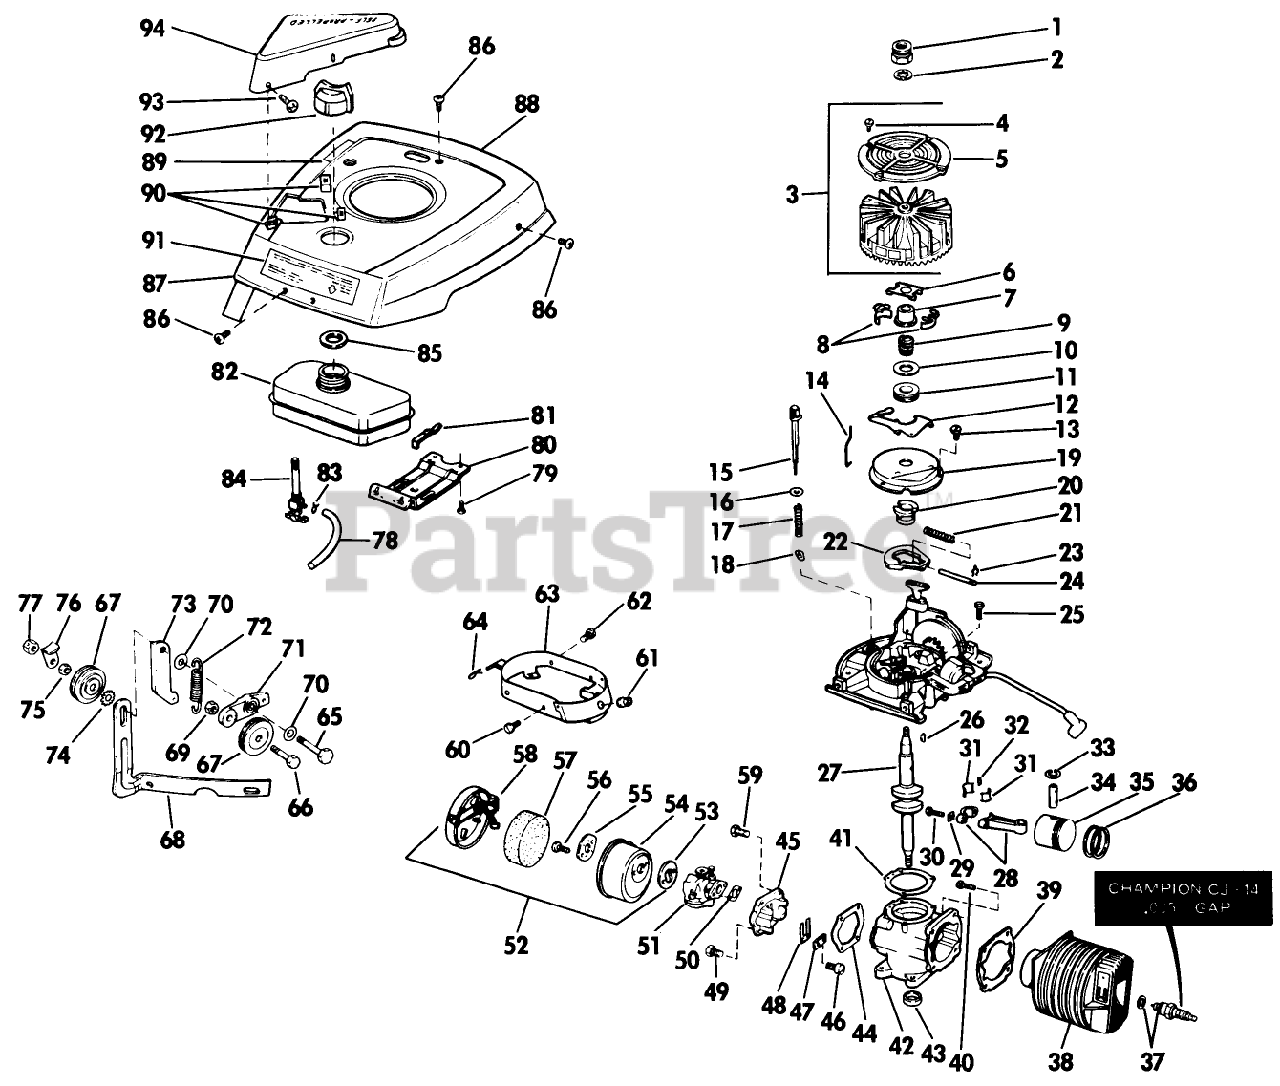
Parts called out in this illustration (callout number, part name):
3	Flywheel Screen Assy.
4	SCREW F
7	COLLAR S
11	THRUST COLLAR S
12	LEVER-GOVERNOR S
13	SCREW S
17	SPRING S
19	DUST COVER S
20	SPARK ADV. S
21	SPARK ADV. SPRING S
22	FLYWEIGHT S
23	SPARK ADJ. SPRING
24	PIN,SPARK ADV. S
31	LINER ASM
33	RING-RETAINING
37	Spark Plug and Gasket
39	GASKET S
41	GASKET S
44	GASKET S
45	REED PLATE AY. S
47	PLATE-BACKUP, REED
49	SCREW S
50	GASKET S
53	GASKET S
56	SCREW S
57	AIR FIL.ELEM S
59	SCREW S
60	SCREW S
61	NUT-CLIP
67	IDLER PULLEY
78	GAS LINE
79	SCREW S
83	CLAMP - HOSE S
84	VALVE&SCREEN SM
86	SCREW S
91	Decal-Instructions
94	BELT COVER AY
